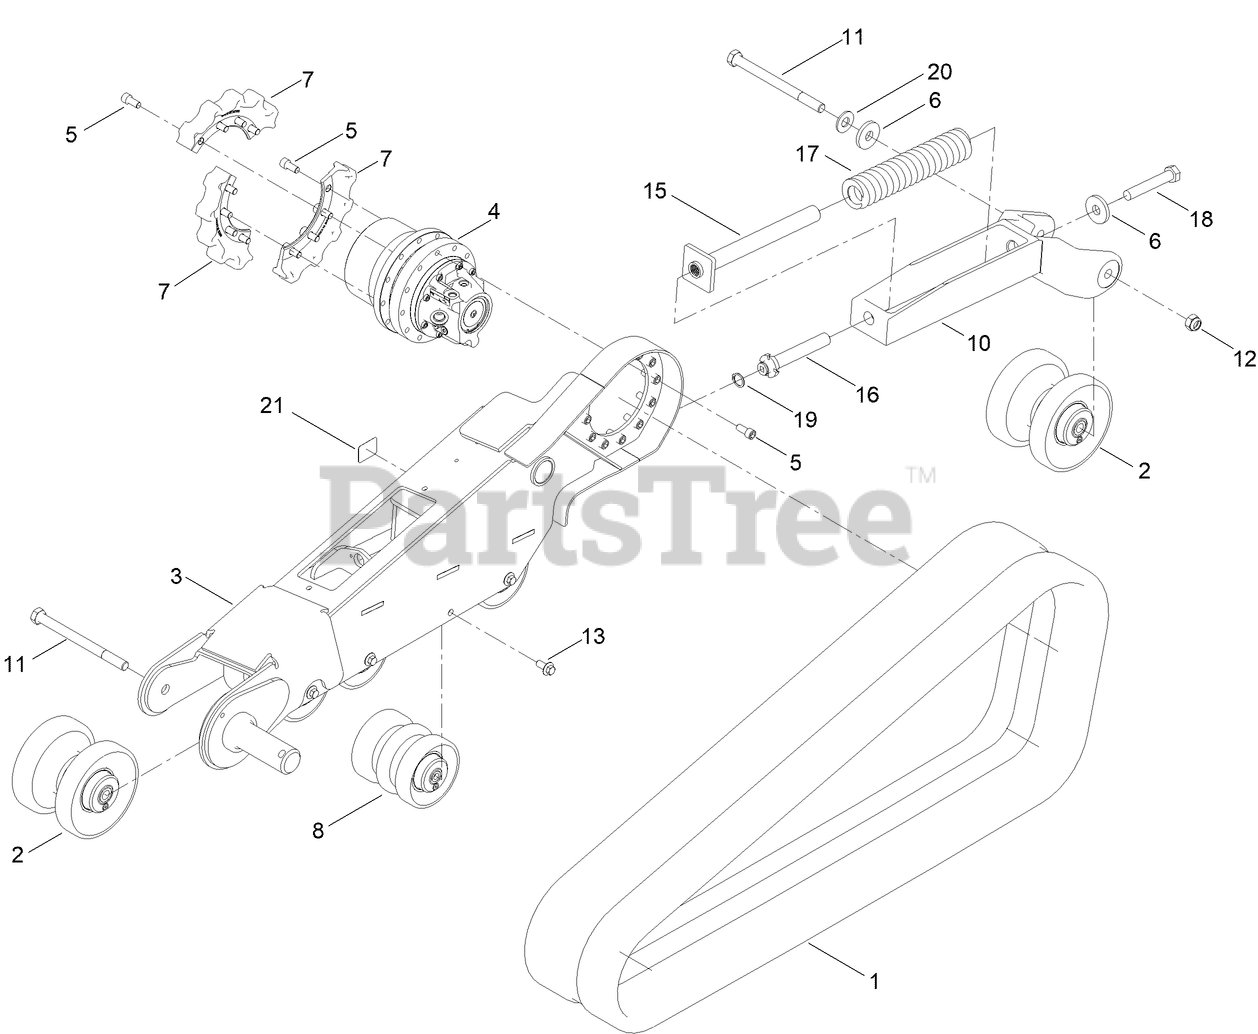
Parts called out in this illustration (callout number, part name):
1	TRACK
2	FRONT WHEEL ASM
3	RH TRACK FRAME ASM
4	DRIVE-TRACK
5	SCREW-HSH
6	WASHER-WHEEL
7	SPROCKET-DRIVE
8	ROAD WHEEL ASM
10	TENSIONER ASM
11	BOLT-HH
12	NUT-HEX
13	SCREW-HHF
15	SPRING CATCH ASM
16	SCREW-TENSIONER
17	SPRING-COMPRESSION
18	BOLT-TAP
19	RING-RETAINING, EXTERNAL
20	WASHER-PLAIN
21	DECAL-TIE DOWN
